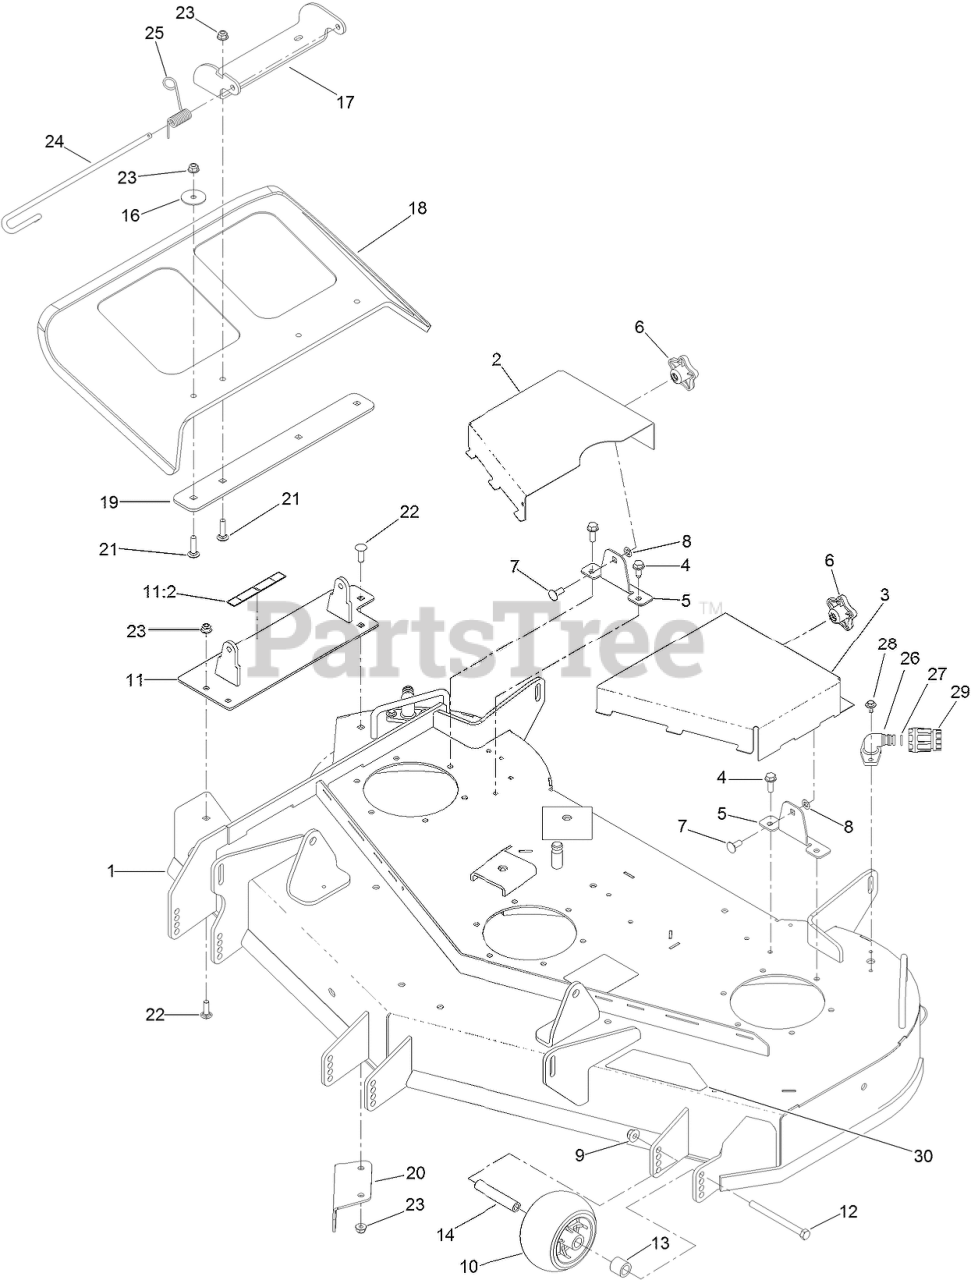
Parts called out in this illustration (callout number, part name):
1	48 INCH DECK ASM
2	COVER-BELT, RH
3	COVER-BELT, LH
4	SCREW-HWHTF
5	BRACKET-SUPPORT
6	KNOB-HANDLE
7	SCREW-CARR
8	RING-RETAINING, BOLT
9	NUT-HF, NI
10	ROLLER-SCALP, ANTI
11	PIVOT-DEFLECTOR
11:2	DECAL-DANGER
12	SCREW-HH
13	SPACER-AXLE, REAR
14	TUBE-SPANNER
16	WASHER-FLAT
17	BRACKET-DEFLECTOR, UPPER
18	DEFLECTOR
19	PLATE-DEFLECTOR
20	BAFFLE-CUTOFF
21	SCREW-CARR
22	SCREW-CARR
23	NUT-HF, NI
24	PIN-CHUTE
25	SPRING-TORSION
26	FITTING-WASHOUT
27	O-RING
28	SCREW-HHFTF
29	CONNECTOR-HOSE
30	DECAL-DECK
